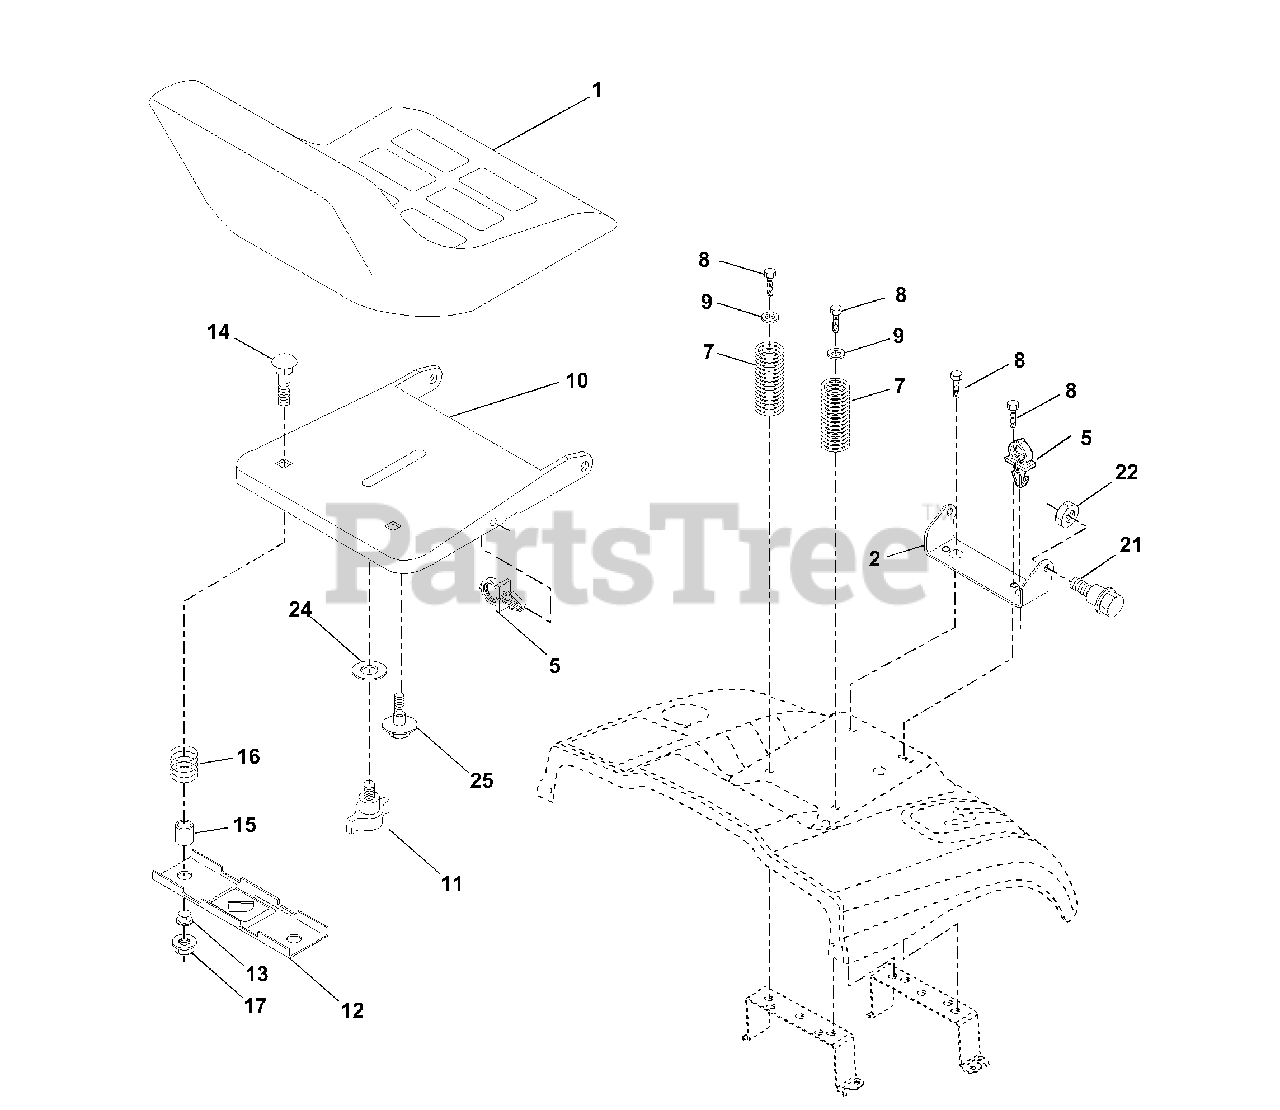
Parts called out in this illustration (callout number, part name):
1	Seat
2	Bracket Pivot Seat 8 720
5	Clip Push-In
7	Spring Seat Cprsn 2 250 Blk Zi
8	Screw 3/8-16 X 1-1/2
9	Washer 13/32 X 1 X 14 Ga.
10	Pan Seat
11	Knob Seat Adj. Wingnut
12	Bracket Mounting Switch
13	Bushing Snap Blk Nyl 50 Id
14	Bolt Rdhd Sqnk 1/4-20x1-1/2
15	Spacer Split 28x .96 Zinc
16	Spring Cprsn
17	Nut Lock 1/4 Lge Flg Gr 5 Zinc
21	Bolt Shoulder 5/16-18 Unc
22	Nut Crownlock 5/16-18
24	Washer 17/32 X 1-3/16 X 12 Ga.
25	Bolt Shoulder 5/16-18 X 62
